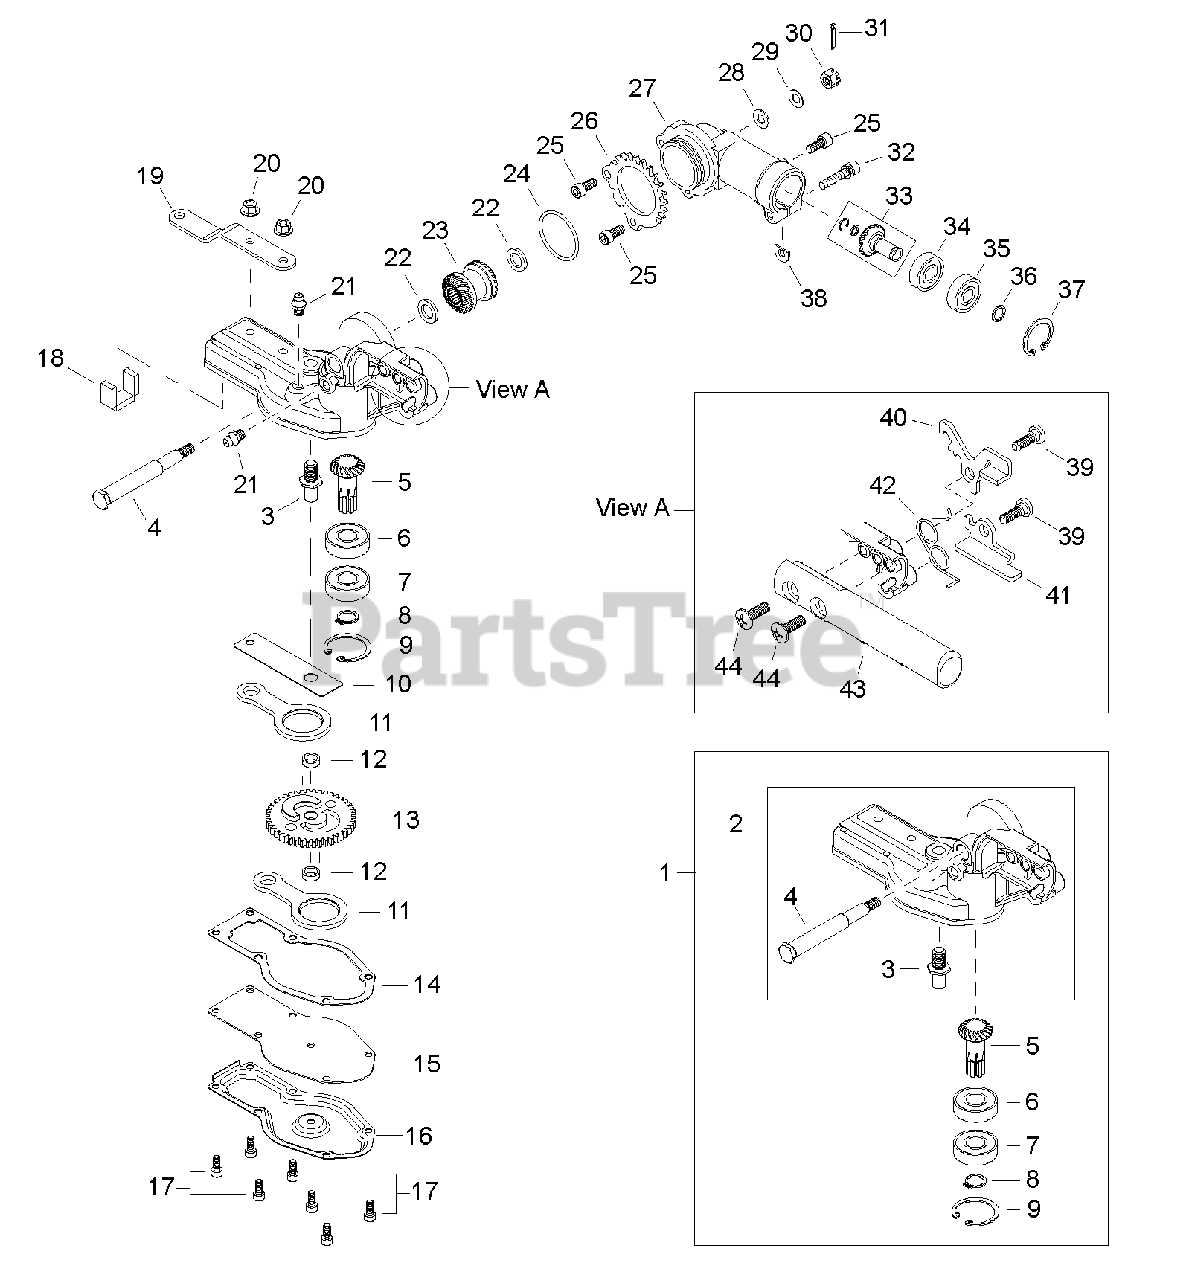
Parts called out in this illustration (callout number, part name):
1	GEAR CASE HOUSING KIT
2	GEAR CASE HOUSING ASSY
3	MAINSHAFT
4	SHAFT
5	SHAFT, PINION
6	BEARING, BALL 6001
7	BEARING, BALL 6001ZZ
8	RING, SNAP Ø12
9	RING, SNAP Ø28
10	PLATE, GUIDE
11	CONROD
12	SPACER Ø11ר8×3.4
13	GEAR, CAM
14	GASKET, GEAR CASE
15	SPACER
16	COVER, GEAR CASE
17	BOLT 4×10
18	PACKING, FELT
19	BRACKET, CUTTER
20	NUT, FLANGE M5
21	FITTING, GREASE
22	COLLAR Ø16ר10×L= 2
23	GEAR, BEVEL
24	O-RING
25	BOLT 5×12
26	RING, LOCKING
27	HOUSING, UPPER GEAR CASE
28	WASHER 6.5×13×1
29	WASHER, CONE M6
30	NUT M6
31	PIN, COTTER Ø1.6×15
32	BOLT M5×25
33	PINION SET, BEVEL
34	BEARING, BALL 609
35	BEARING, BALL 609ZZ
36	RING, SNAP
37	RING, SNAP Ø24
38	D-WASHER
39	BOLT M6
40	LEVER, LOCK
41	RELEASE, LOCK
42	SPRING, TORSION
43	LEVER, ADJUSTMENT
44	SCREW, TRUSS M6×20
